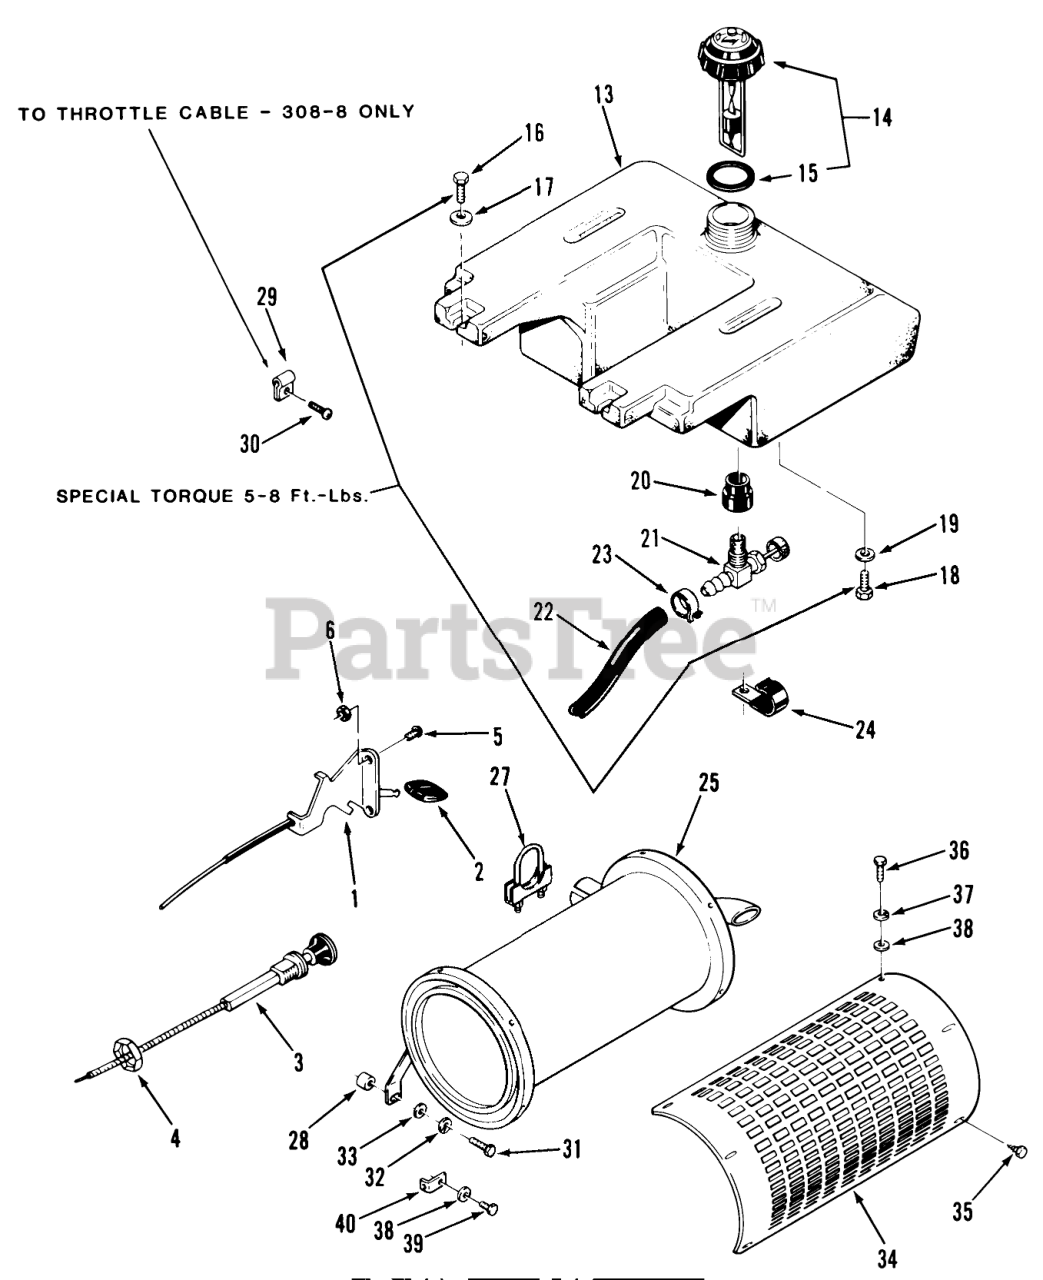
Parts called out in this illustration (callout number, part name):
1	Throttle Control 310, 312, 414
1	Throttle Control 308
1	CONTROL THROTTLE
2	KNOB-THROTTLE
3	CONTROL CHOKE
4	NUT-HEX PALNUT
5	SCRW-PHC
6	Nut
13	TANK-FUEL
14	ASSY-GAUGE CAP
15	GASKET-GAS CAP
16	Bolt
17	Washer
18	Bolt
19	Lockwasher
20	BUSHING
21	VALVE-FUEL
22	Fuel Line
22	Line-Fuel 62"
23	Clamp
24	Clamp
24	CLAMP
25	MUFFLER
25	Muffler
27	CLAMP-1 1/2
28	SPACER
29	CLIP-CABLE
30	Screw, P.H.C.R. #8-32 x2/8
31	Bolt
32	Lockwasher
33	WASHER 5/16 SAE
34	SHIELD
34	SHIELD-MUFFLER
35	BOLT-HEX #10 X 3/8
36	HEX HEAD CAP SCREW -
37	Washer
39	Bolt
40	Clip 418-8,418-A
